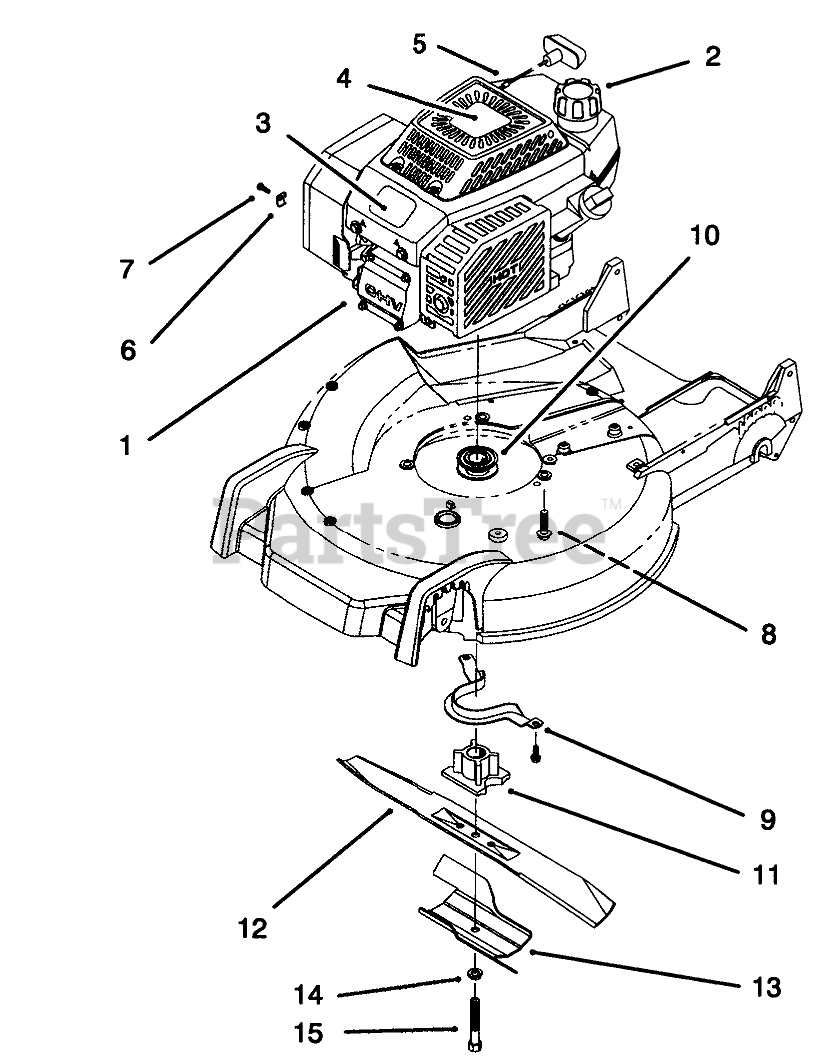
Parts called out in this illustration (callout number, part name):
1	Engine
2	GAS CAP ASM
3	PLATE-LOGO
4	DECAL - RECOIL
5	STOP-ROPE
6	CLAMP-CASING
7	SCREW-CLAMP
8	SCREW-HWH
9	Guide-Belt
10	PULLEY-DRIVE, ZONE START
11	RETAINER - BLADE
12	Blade
13	Stiffener-Blade
14	WASHER-LOCK
15	SCREW-BLADE
